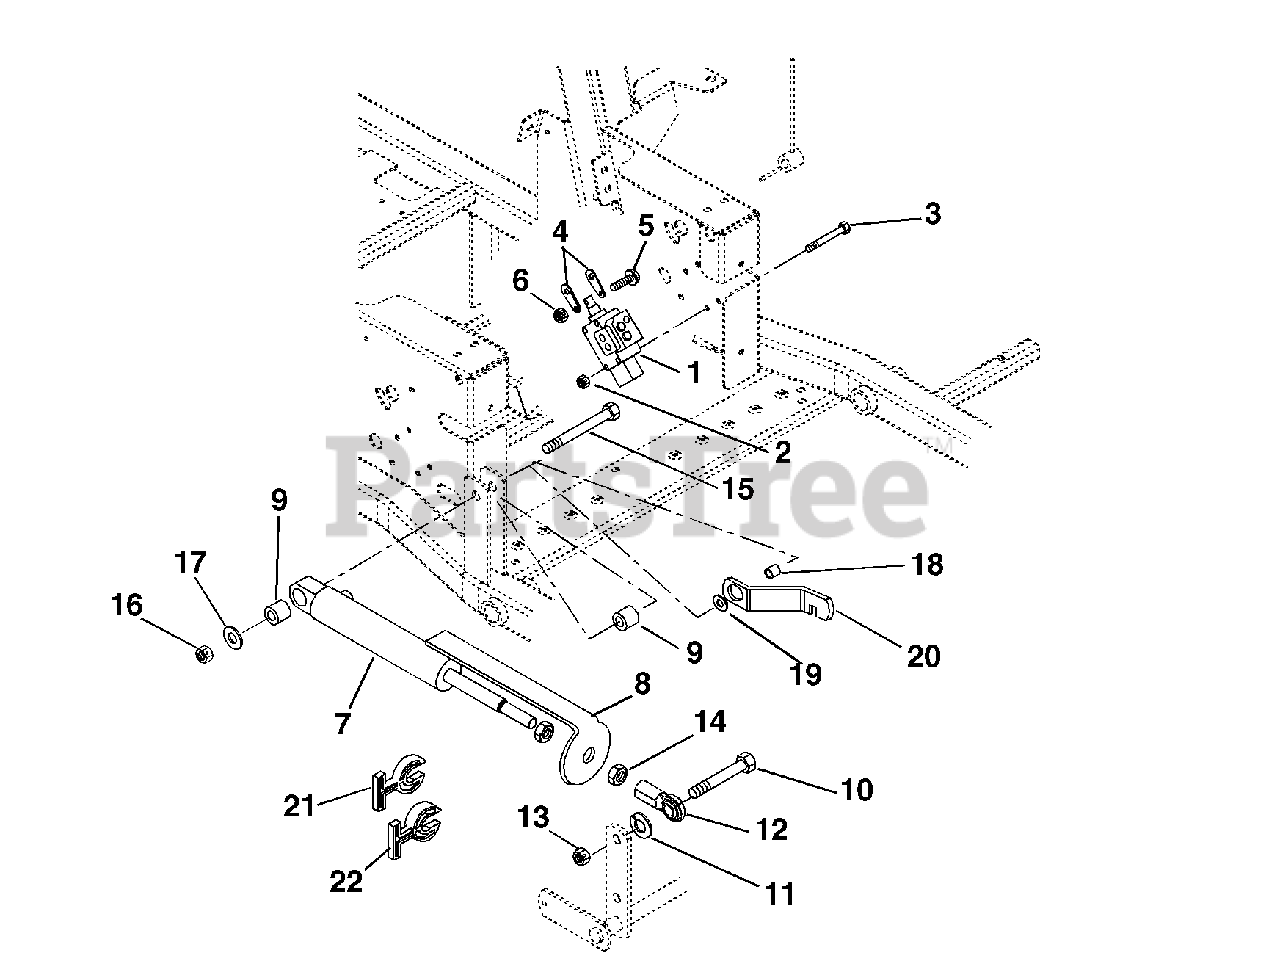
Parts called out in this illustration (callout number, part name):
1	Valve, Hydraulic Lift
2	Nut-Locking-Nylon .25-20
3	Bolt-Hex .25-20 x 2.75 Grade 5
5	Screw-Machine 10-24 x 1.00 Hex Washer Head
6	Nut-Locking-Nylon 10-24 with Insert
7	Cylinder-Hydraulic Lift
8	Strap-Height of Cut Indicator
9	Bushing .516 x 1.000 x 1.050
10	Bolt-Hex .62-11 x 2.25 Grade 8
11	Washer-Lock .62 x .156
12	Rod End-Right Hand-Female 5/8
13	Nut-Locking-Center .62-11
14	Nut-Jam .625-18
15	Bolt-Hex .50-13 x 3.75 Grade 5
16	Nut-Locking-Center .50-13
17	Washer-Flat-Steel .515 x 1.625 x .25
18	Bushing-Flange .515 x .75 x .275 x 1.12
19	Wave-Washer .76 x 1.12 x .08
21	Stop, Cylinder .34 Thick
22	Stop, Cylinder .68 Thick
